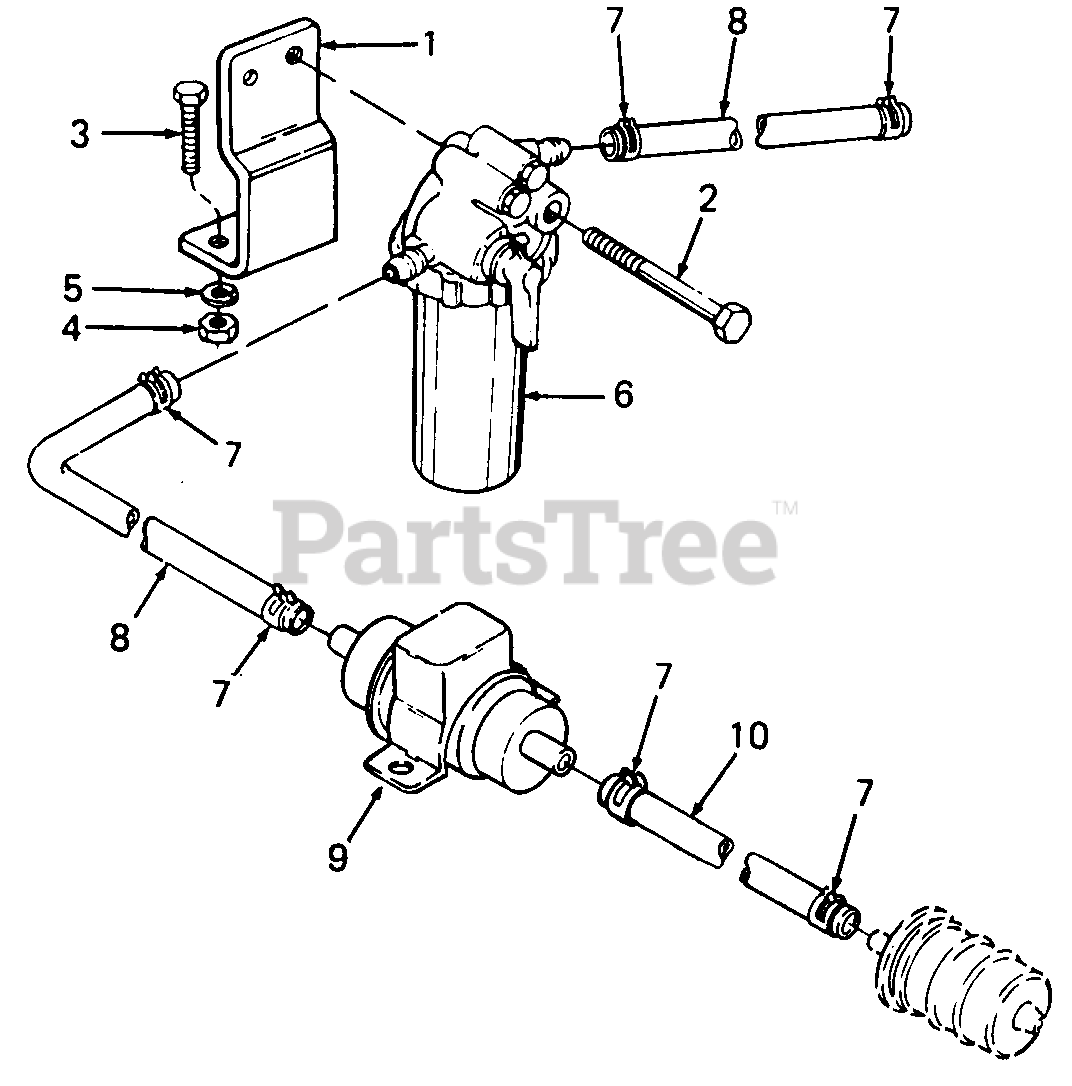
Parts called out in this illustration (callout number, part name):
1	Bracket, Fuel Filter
2	Screw, Hex Cap, 5/16-18 X 2.5 Lg
3	Screw, Hex Cap, 5/16-18 X 1.0 Lg GR5
4	Nut, Hex, 5/16-18
5	Washer, Lock, 5/16
6	Filter, Fuel
7	Clamp, Hose
8	Fuel Line - 9.0" Lg
9	Fuel Pump, Electric
10	Fuel Line - 2.0 " Lg
